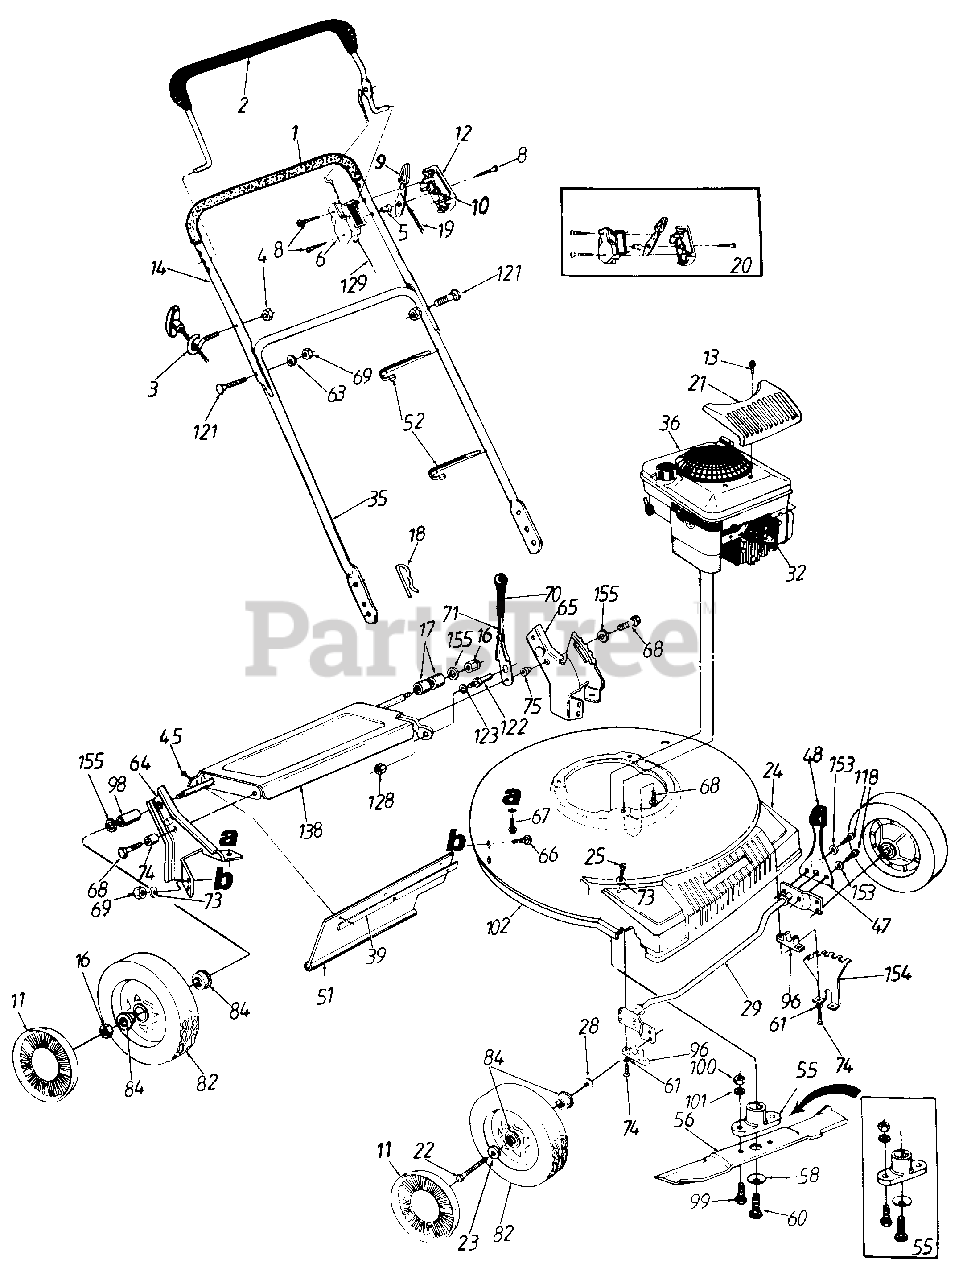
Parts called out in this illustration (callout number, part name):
1	Grip
2	Control Handle Ass'y.
3	Rope Guide Bolt
4	Hex L-Nut 1/4-20 Thd.
5	Control Disc Pin
6	Clutch Panel Half
8	Truss Mach Scr. #12 x 1.5" Lg.
9	Throttle Control Lever
10	Control Panel Half
11	Hub Cap
12	Throttle Control Label
13	Truss Hd. AB-Tap Scr. #6 x .62" Lg.
14	Upper Handle
16	Hex Ins. L-Nut 3/8-16 Thd.
17	Spacer .526" I.D. x .64" Lg.
18	Internal Cotter Pin 5/16" Dia.
19	Throttle Control Wire 51" Lg.
20	Kit Control Housing Comp.
21	Engine Cover
22	Front Axle Bolt
23	Wave Wash. .53" I.D. x .78"
24	Plastic Front End
25	Truss B-Tap Scr. 5/16 x .75" Lg.
28	Bell-Wash. .38" I.D. x .88"
35	Lower Handle
36	Engine
39	Retaining Strip
45	Hex AB-Tap Scr. 1/4 X .62"
47	Spring Lever
48	Knob
51	Rear Flap 3.75" x 17.30" Lg.
52	Cable Tie
55	Blade Adapter Kit
56	21" Mulching Blade
58	Bell-Wash. .47" I.D. x 1.14" O.D.
60	Hex Bolt 7/16-20 x 2.5"
61	L-Wash. 1/4" I.D.
63	L-Wash. 5/16" I.D.
64	R.H. Handle Wheel Brkt. Ass'y.
65	L.H. Handle Wheel Brkt. Ass'y.
66	Carriage Bolt 5/16-18 x .62
67	Hex B-Tap Scr. 5/16-18
68	Hex TT-Tap Scr. 3/8-16
69	Hex Nut 5/16-18 Thd.
71	Height Adj. Lever
73	Bell-Wash. 5/16" I.D.
74	Hex Wash. Hd. B-Tap Scr. 1/4-20 x 1" Lg.
75	Shld. Spacer .5" Dia.
82	Wheel Ass'y. Comp. Rear
84	Ball Bearing 1/2" I.D.
96	Block Bushing
98	Sleeve.526" I.D.
99	Hex Bolt 3/8-24 x 1.0" Lg.
100	Hex Nut 3/8-24 Thd.
101	L-Wash. 3/8" I.D.
121	Curved Carr. Bolt 5/16-18 x 1.38" Lg.
122	Shld. Pin 1.43" Lg.
123	L-Wash. 3/8" I.D.
128	Hex Jam Nut 3/8-24 Thd.
129	Control Cable 39"
138	Rear Axle Ass'y.
153	External L-Wash. 1/4" I.D.
154	Height Adj. Brkt.
155	Fl-Wash. .385" I.D. x .37" O.D.
